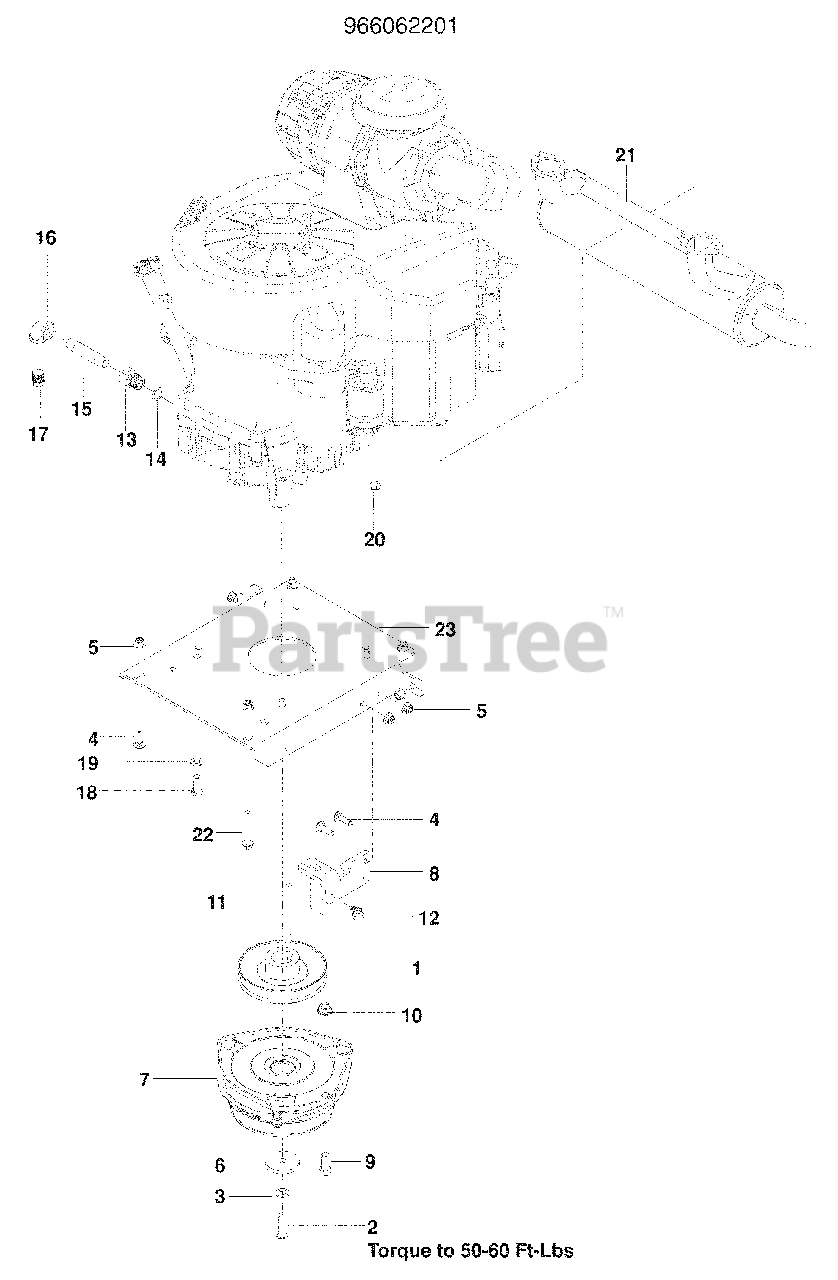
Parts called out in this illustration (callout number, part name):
1	PULLEY, ENGINE
2	BOLT 7/16-20 x 1½ HEX NYL
3	WASHER 7/16 SLW
4	BOLT 5/16-18 x 1 RD HD
5	NUT 5/16-18 HEX FLG NYLOC
6	WASHER, BLADE
7	CLUTCH, GT 3.5
8	STOP, CLUTCH
9	BOLT 7/16-14 x 1 HEX NYLOC
10	NUT 7/16-14 HEX WHIZ LK
11	KEY ¼ SQ x 3½
12	TIE WRAP w/ CLIP
13	ADAPTOR, OIL DRAIN
15	PIPE 3/8 NPT x 3"
17	PLUG, DRAIN, 3/8 NPTF
18	BOLT 3/8-16 x 1 HEX NYLOC
19	WASHER 3/8 SPRING
20	NUT M8 x 1.25 NYLOC
22	SCREW 5/16-18 x 2¼ HEX FLG
23	PLATE, ENGINE
